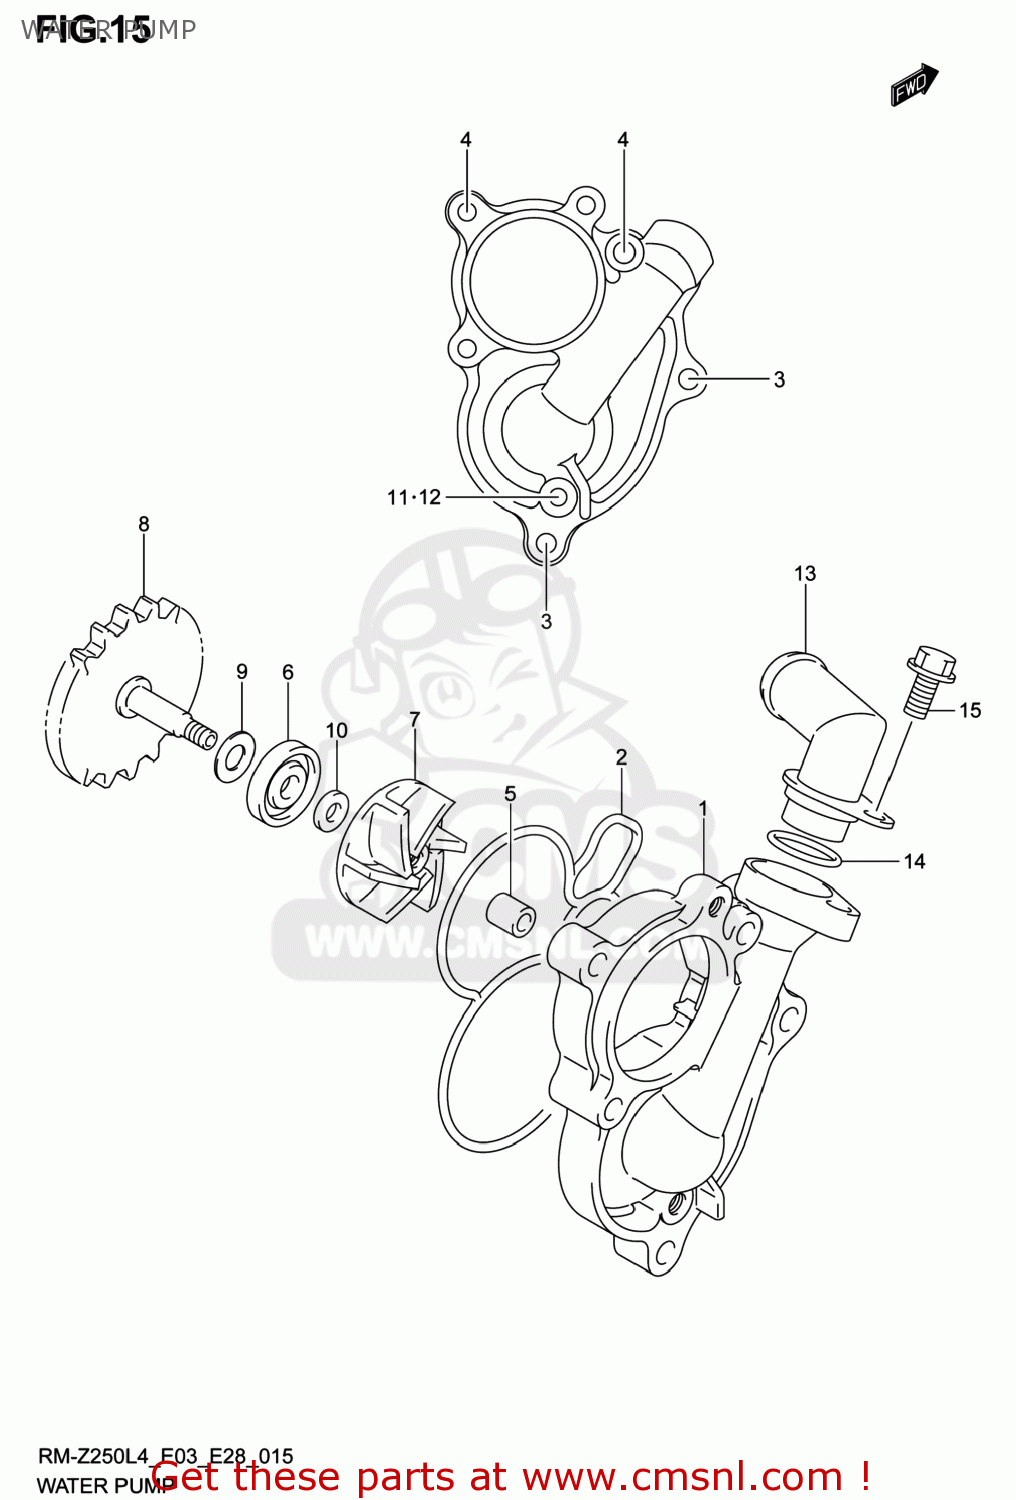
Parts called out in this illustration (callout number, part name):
1	CASE,WATER PUMP
2	O RING,WATER PUMP CASE
3	BOLT
4	BOLT
5	PIN
6	SEAL,WATER PUMP OIL
7	IMPELLER,WATER PUMP
8	SHAFT,WATER PUMP
9	SHIM(8X18X0.5)
10	SHIM(6X14X1)
11	BOLT
12	GASKET(5.8X13X1.2) (NAS)
13	JOINT,WATER PUMP
14	O RING(D:2.4,ID:16.8)
15	BOLT
